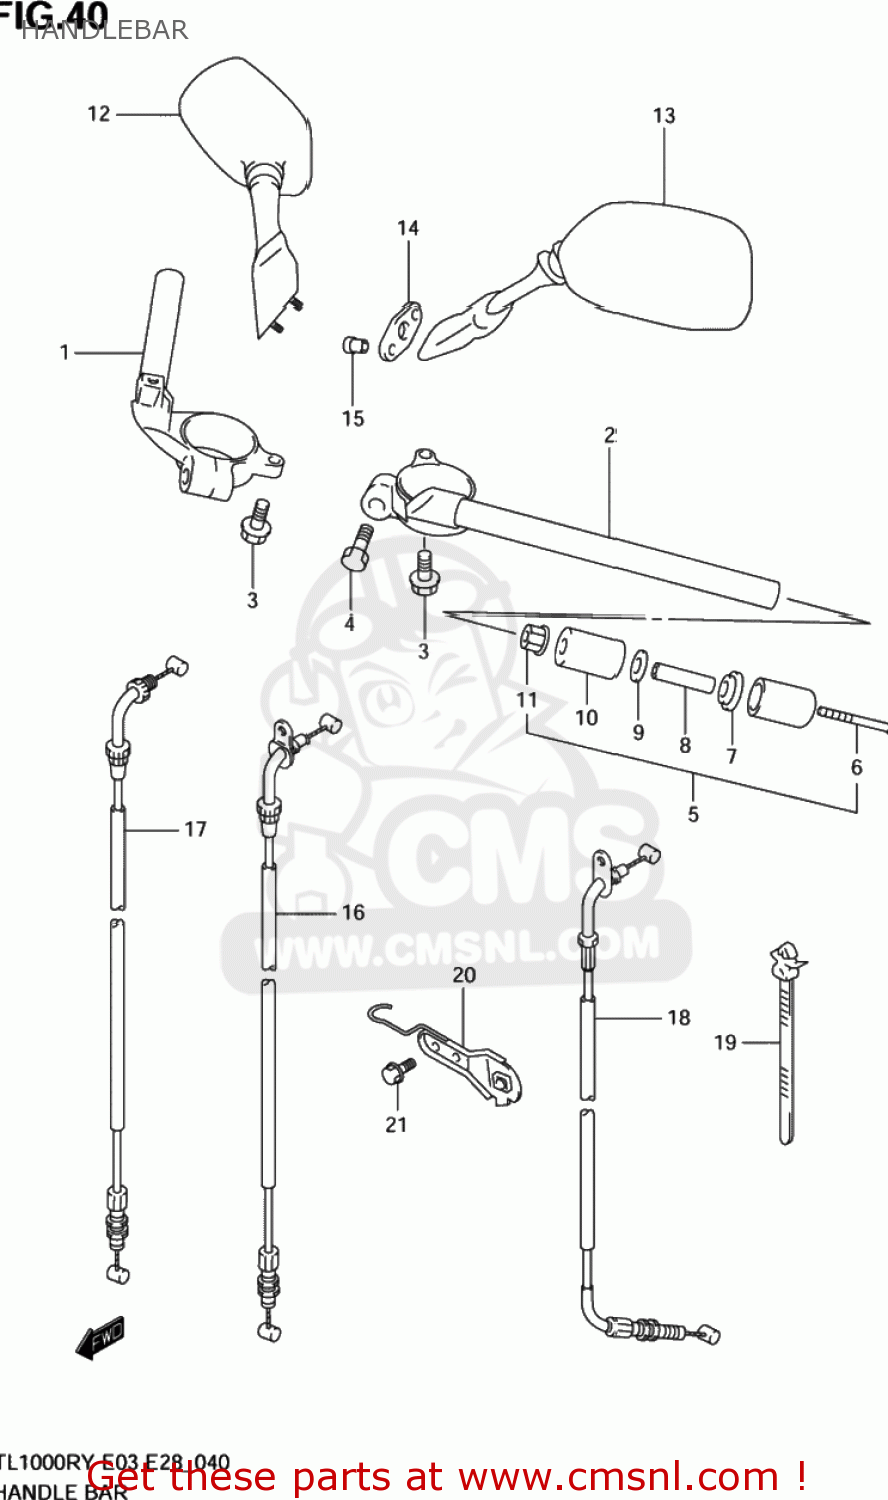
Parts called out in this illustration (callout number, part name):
1	HANDLEBAR,R
2	HANDLEBAR,L
3	BOLT
4	BOLT(8X30)
5	BALANCER SET,HANDLEBAR
6	SCREW(6X110)
7	EXPANDER,HANDLE BALANCER
8	SPACER,EXPANDER
9	WASHER(6.5X14X2)
10	EXPANDER,HANDLE BALANCER
11	NUT
12	MIRROR ASSY,RR VIEW,R
13	MIRROR ASSY,RR VIEW,L
14	CUSHION,RR VIEW MIRRORR
15	NUT,RR VIEW MIRROR
16	CABLE ASSY,THROTTLE NO.1
17	CABLE ASSY,THROTTLE NO.2
18	CABLE,STARTER
19	CLAMP(L:165)
20	GUIDE,CABLE
21	BOLT
